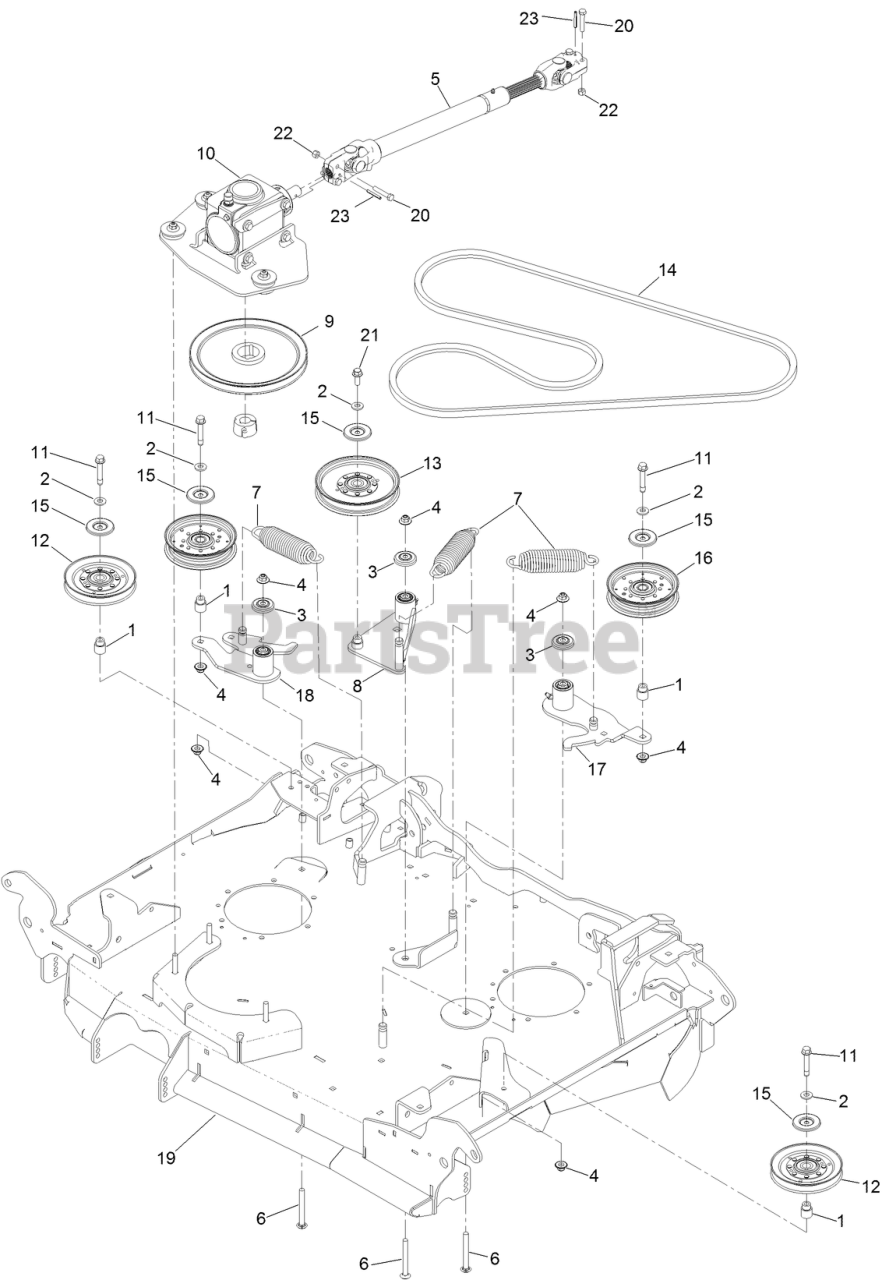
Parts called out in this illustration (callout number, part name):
1	BUSHING-IDLER
2	WASHER-BELLEVILLE
3	GUARD-TOP
4	NUT-FLANGE, NI
5	DRIVESHAFT ASM
6	BOLT-SHOULDER, CARRIAGE
7	SPRING-EXTENSION
8	IDLER ARM ASM
9	PULLEY
11	SCREW-HHF W/ PATCH
12	IDLER-V
13	IDLER-PULLEY
14	V-BELT
15	SHIELD-DUST
16	PULLEY-IDLER, FLAT
17	IDLER ASM
18	IDLER ASM
19	CENTER DECK ASM
20	SCREW-HH
21	SCREW-HHF
22	NUT-LOCK, NI
23	PIN-ROLL
